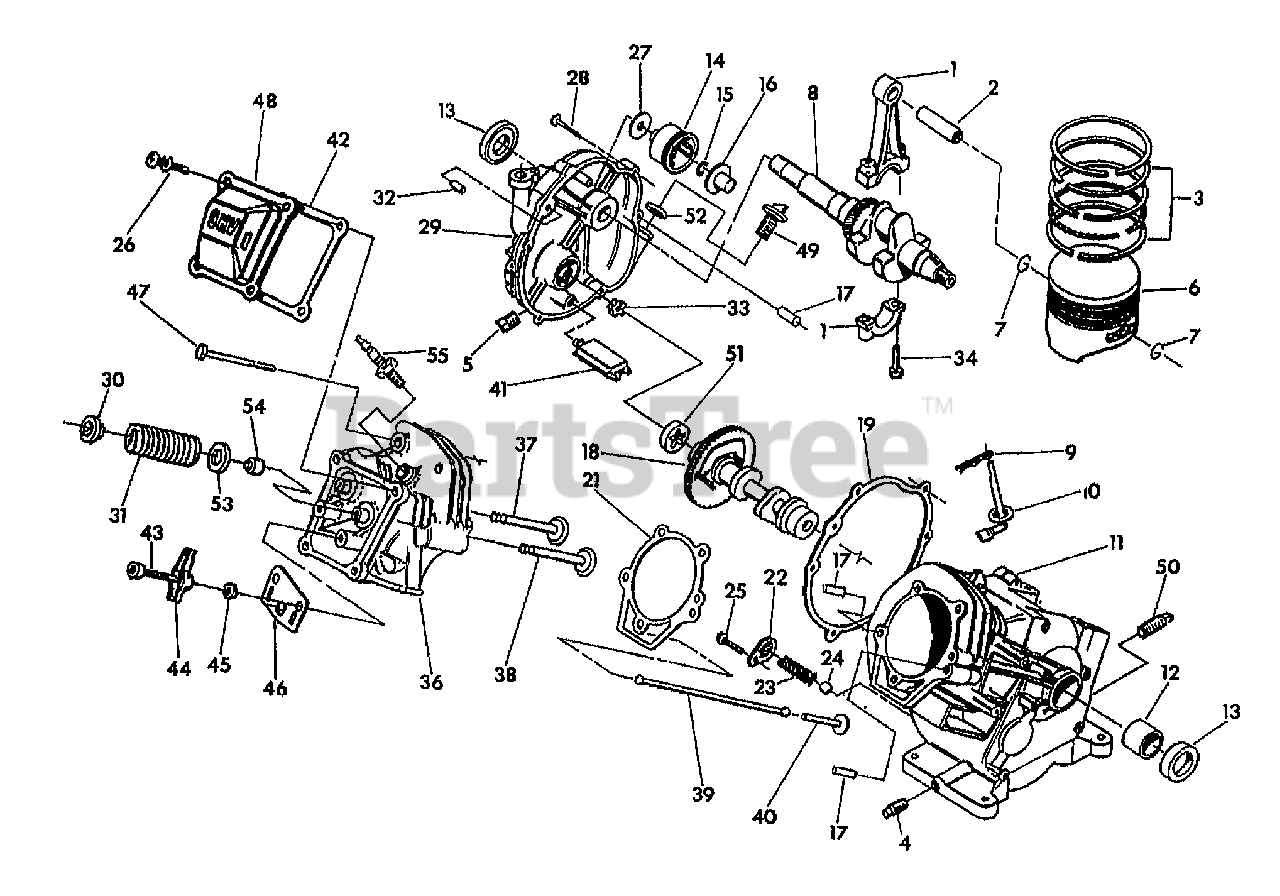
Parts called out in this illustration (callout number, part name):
1	ROD-CONNECTING W/CAP
2	PIN-PISTON
3	PISTON RING SET (4000W GEN)
4	PLUG-1/4" MAGNETIC PIPE
5	PLUG-1/8" NPTF PIPE
6	PISTON (4000W GENERATOR)
7	RETAINER-PISTON PIN
8	ASSM-CRANKSHFT W/GEAR(UNIV TAP
9	PIN-"R" GOVERNOR ARM
10	ARM-GOVERNOR
11	SUBASSM-CRANKCASE (4000W GEN)
12	BEARING-SLEEVE
13	SEAL-CRANKSHAFT
14	ASSM-GEAR GOVERNOR
15	RETAINER-GOVERNOR ("C" RING)
16	SPOOL-GOVERNOR
17	DOWEL-10"DIA. SLEEVE (PRS WSHR
18	ASSM-CAMSHAFT
19	GASKET-CRANKCASE
21	GASKET-CYLINDER HEAD
22	RETAINER-SPRING OIL PRESS.
23	SPRING-OIL PRESSURE
24	BALL-PRESSURE RELIEF
25	SCR M5-0.8X8MM (THD FORMING)
26	SCR M6-1.0X12MM
27	WASHER-THRUST
28	SCR-HFLK
29	SUBASSM-GEAR COVER
30	RETAINER-VALVE SPRING
31	SPRING-VALVE
32	PIN-DOWEL M12X20
33	GEROTOR-INNER
34	BOLT-CONNECTING ROD
36	CYL HEAD W/VALVE SEATS & GUIDE
37	VALVE-EXHAUST
38	VALVE-INTAKE
39	ROD-PUSH GEN #88396A
41	ASSM-OIL PICKUP
42	GASKET-ROCKER COVER
43	STUD-PIVOT BALL
44	ARM-ROCKER
45	NUT-HEX/JAM (ROCKER ARM)
46	PLATE-PUSH ROD GUIDE
47	SCR-M8X50MM HEAD
48	ASSM-ROCKER CVR BREATHER
49	PLUG-OIL FILL
50	PLUG-1/4" NPT PIPE
51	GEROTOR-OUTER 6/5
52	RING-O 17.8MM IDX2.4MM
53	WASHER-VALVE SPRING
54	SEAL-VALVE STEM
